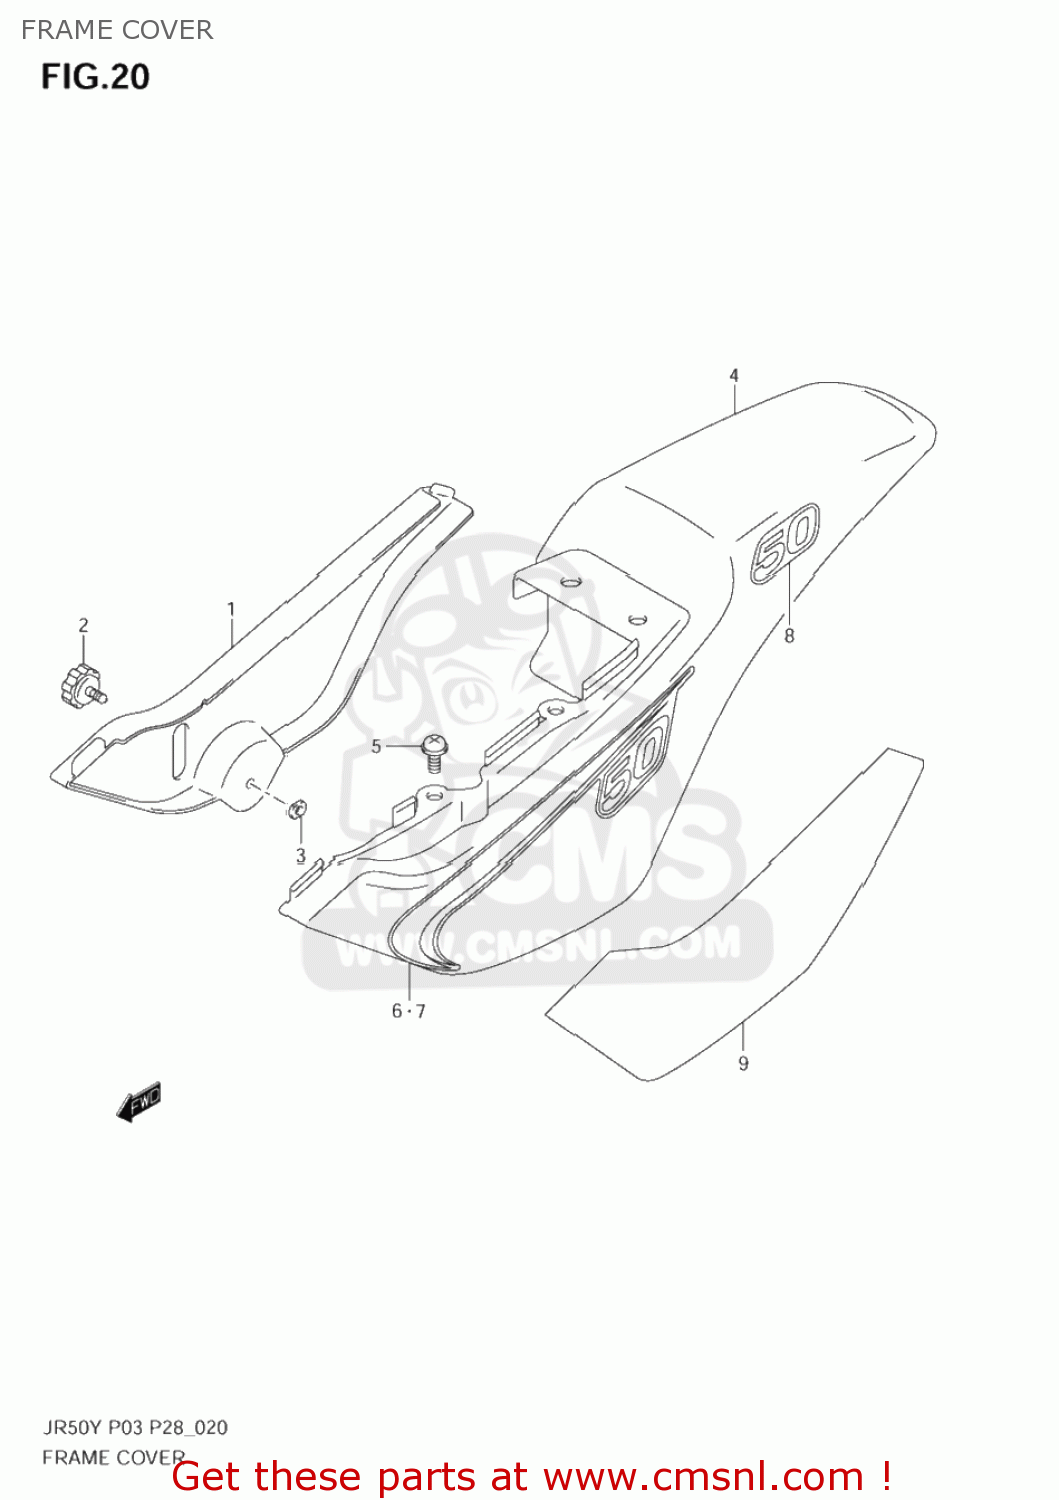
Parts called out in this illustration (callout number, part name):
1	COVER,FRAME,R(WHITE)
2	KNOB,FRAME COVER,R
3	NUT
4	COVER,FRAME,L(YELLOW)
5	SCREW(6X16)
6	TAPE,FRAME COVER,R
7	TAPE,FRAME COVER,L
8	EMBLEM,FRAME COVER
9	TAPE,FRAME COVER,L
